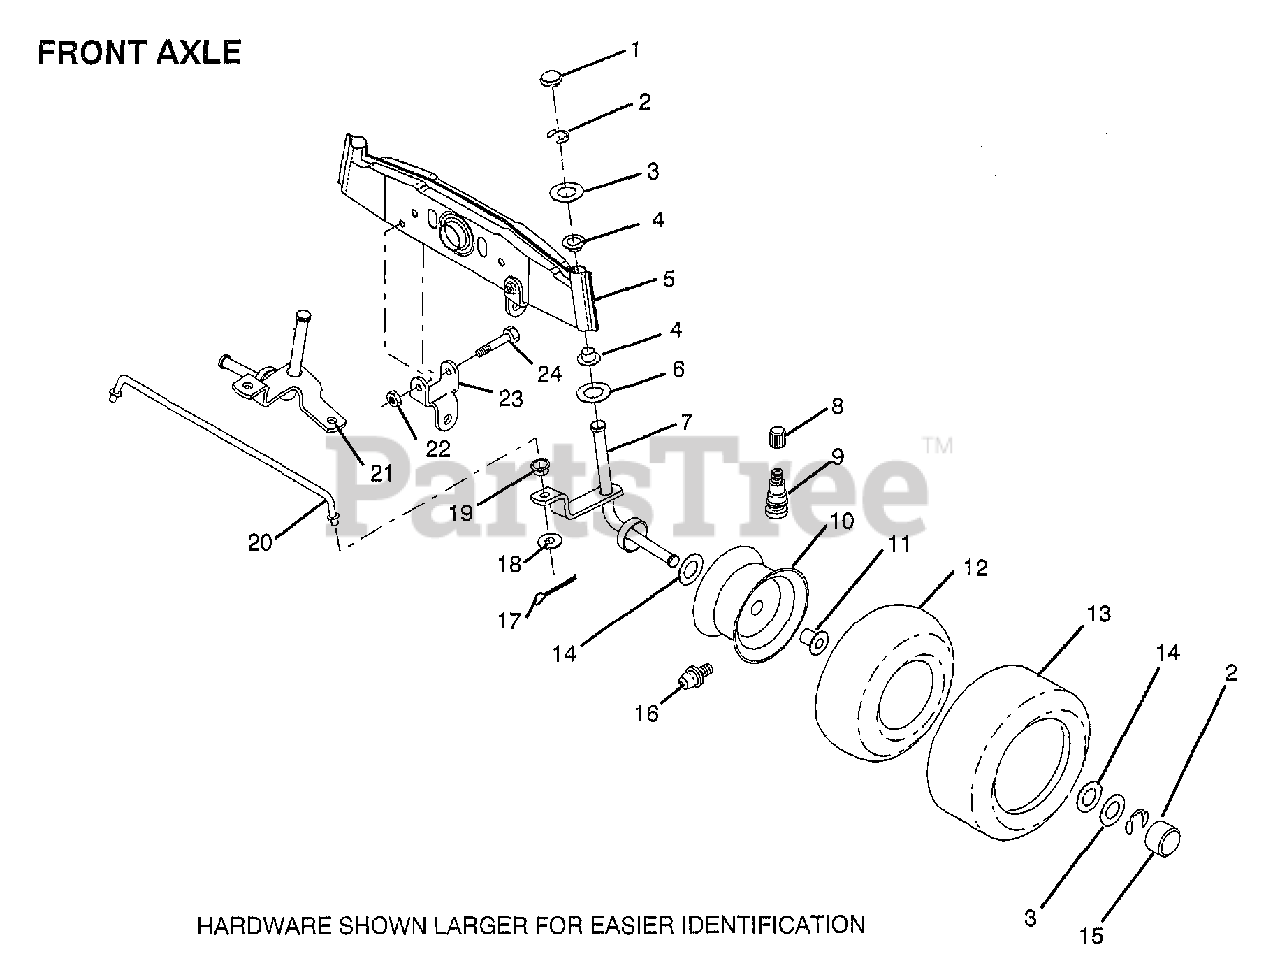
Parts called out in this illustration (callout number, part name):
1	CAP
2	RING
3	WASHER
4	NYLINER
5	AXLE FRONT
6	WASHER .T
7	SPINDLE RH
8	VALVE CAP
9	VALVE STEM LT
11	"FLANGE, BEARING"
12	TUBE.5.3/4.5/6
13	TIRE
14	WASHER
15	HUB CAP
16	FITTING LT
17	COTTER PIN
18	WASHER
19	BUSHING.DRAGLINK
20	ROD TIE
21	SPINDLE LH
23	"BRKT,FRONT STAB"
24	BOLT
